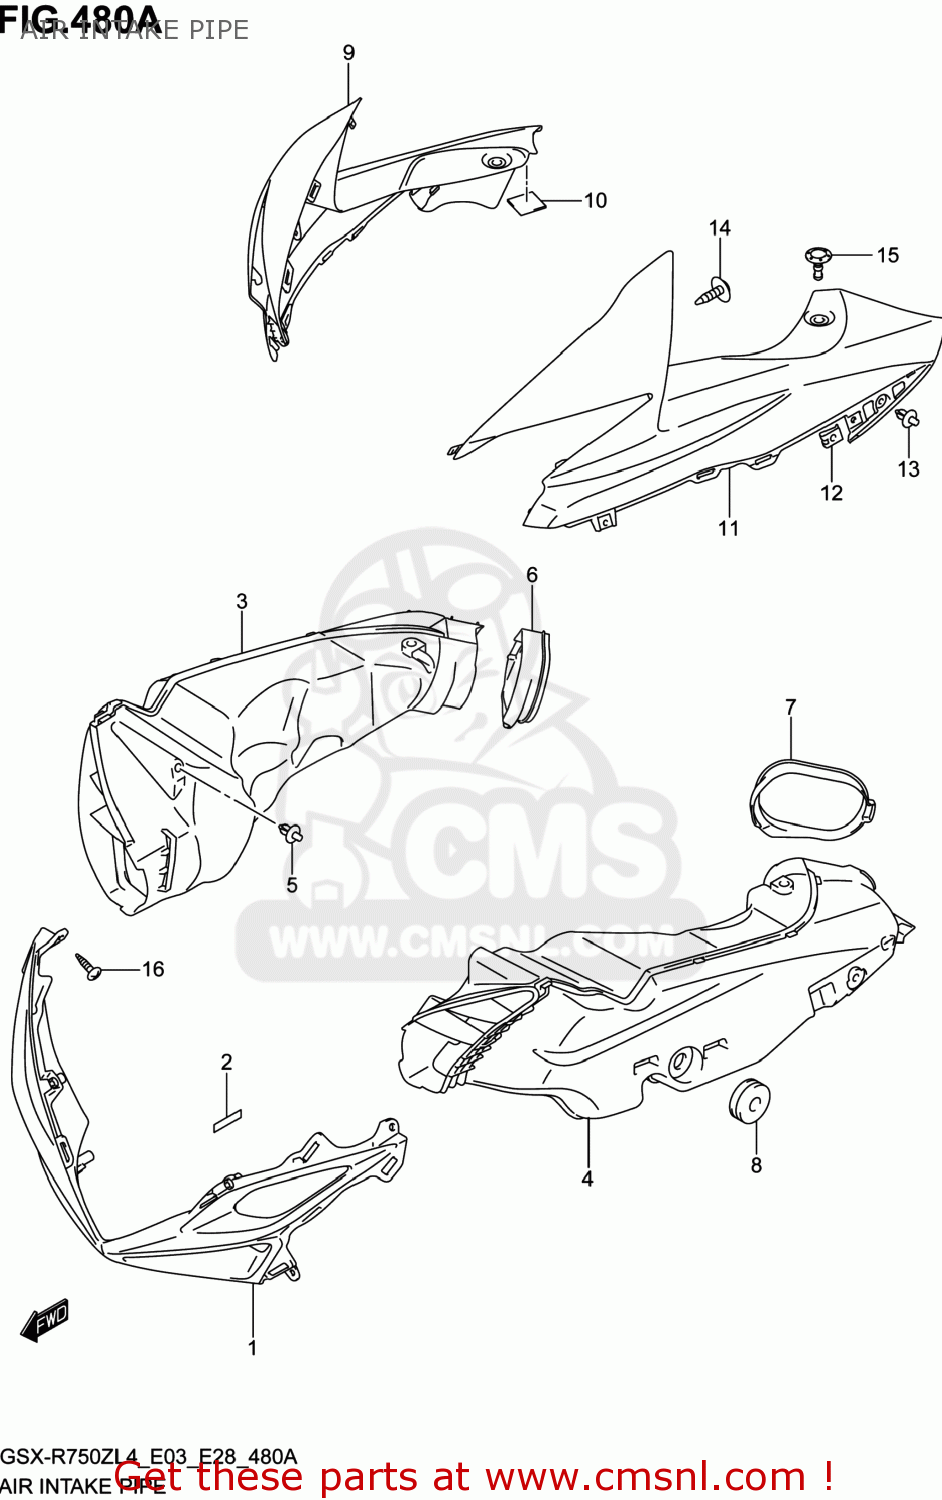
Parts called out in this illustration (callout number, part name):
1	COVER,INTAKE
2	TAPE(6X25X0.13)
3	PIPE,AIR INTAKE,R
4	PIPE,AIR INTAKE,L
5	CLIP(BLACK)
6	MOLDING,AIR INTAKE,R
7	MOLDING,AIR INTAKE,L
8	CUSHION
9	COVER,INTAKE,R
10	PROTECTOR,BATTERY
11	COVER,INTAKE,L
12	NUT
13	CLIP(BLACK)
14	SCREW(5X12)
15	CLIP
16	SCREW
